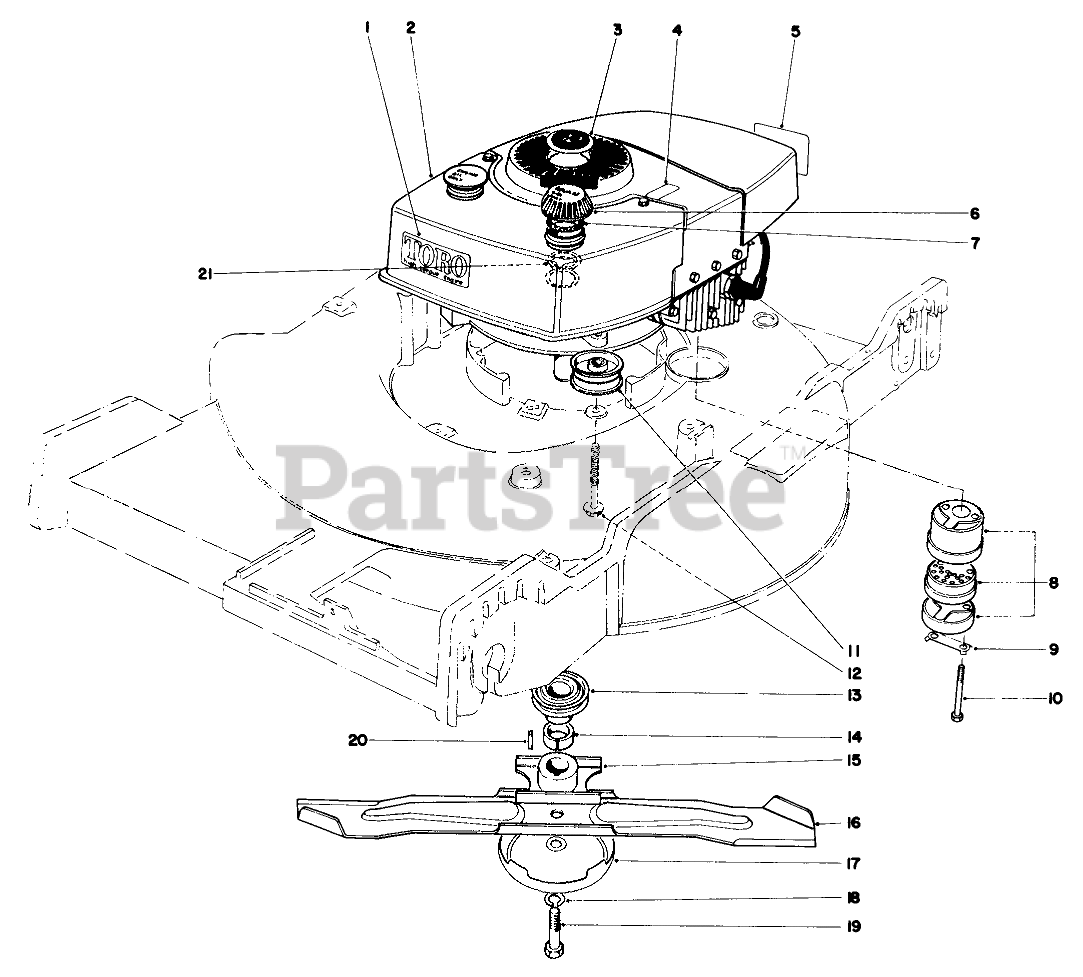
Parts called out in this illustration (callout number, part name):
1	High Torque
2	Engine
3	Plug Button
4	Decal Lockout
5	Decal Maintenance
6	Gas Cap Assy. (Incl. #7 & 21)
7	GASKET
8	Muffler Assy. (Incl. #9 & 10)
9	CLIP - LOCKING
10	SCREW-HH
11	IDLER PULLEY
12	3/8-16 X 2-3/4 CAPSCR
13	PULLEY DRIVER
14	Pulley Spacer
15	BLADE RETAINER WA
16	Blade
17	AntiScalp Cup
18	WASHER-LOCK
19	BLADE SCREW
20	KEY-SQUARE
21	GAS CAP BAFFLE
